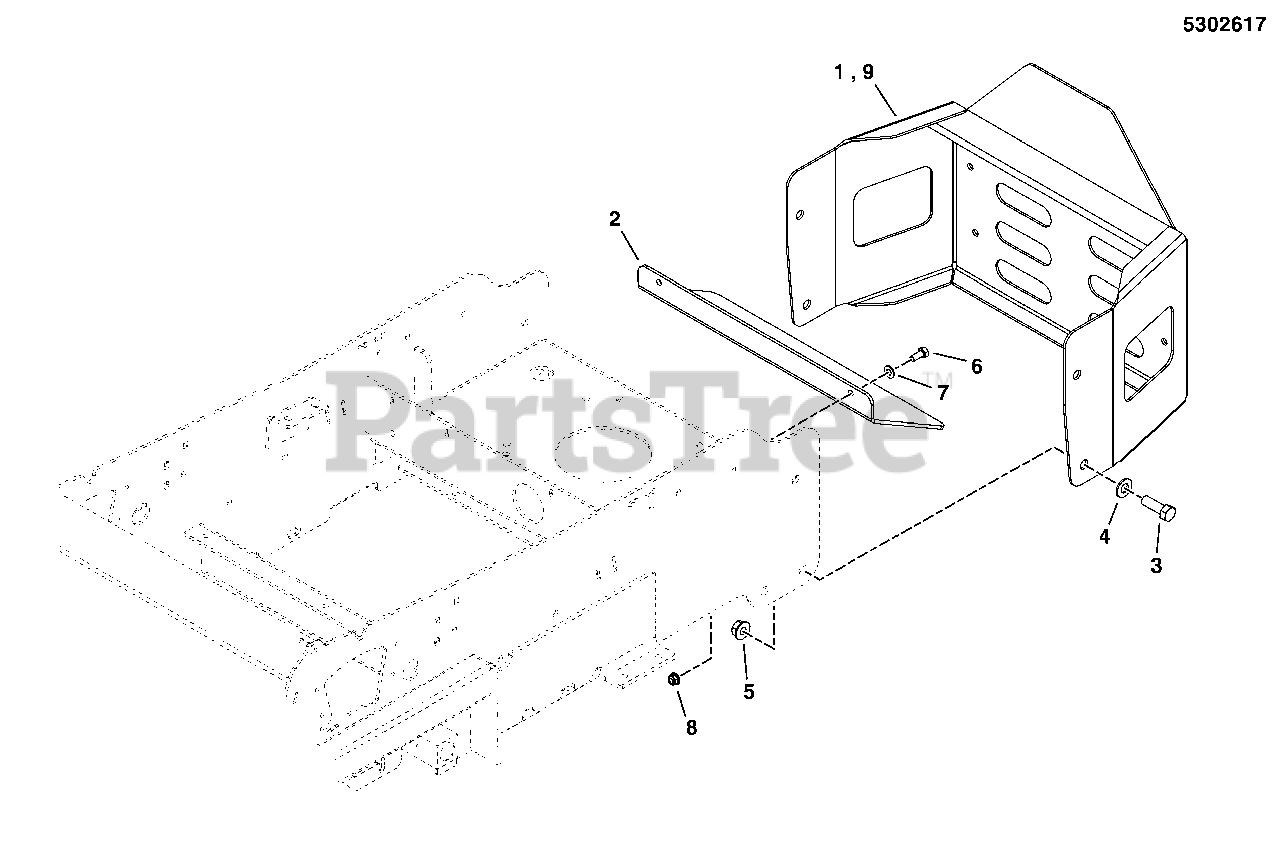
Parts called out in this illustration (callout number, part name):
1	WELD, PLATE, BUMPER - RED
2	SHIELD, MUFFLER - BLK
3	BOLT, 1/2-13 X 1-1/2 GD5 YZ
4	WASHER, 1/2 SAE
5	NUT, 1/2-13 HEX NYLOCK FLANGE
6	BOLT, 5/16-18 X 3/4 GD5
7	WASHER, 5/16 SAE
8	NUT, 5/16-18 HEX NYLOCK FLANGE
9	WELD, PLATE, BUMPER - RED
